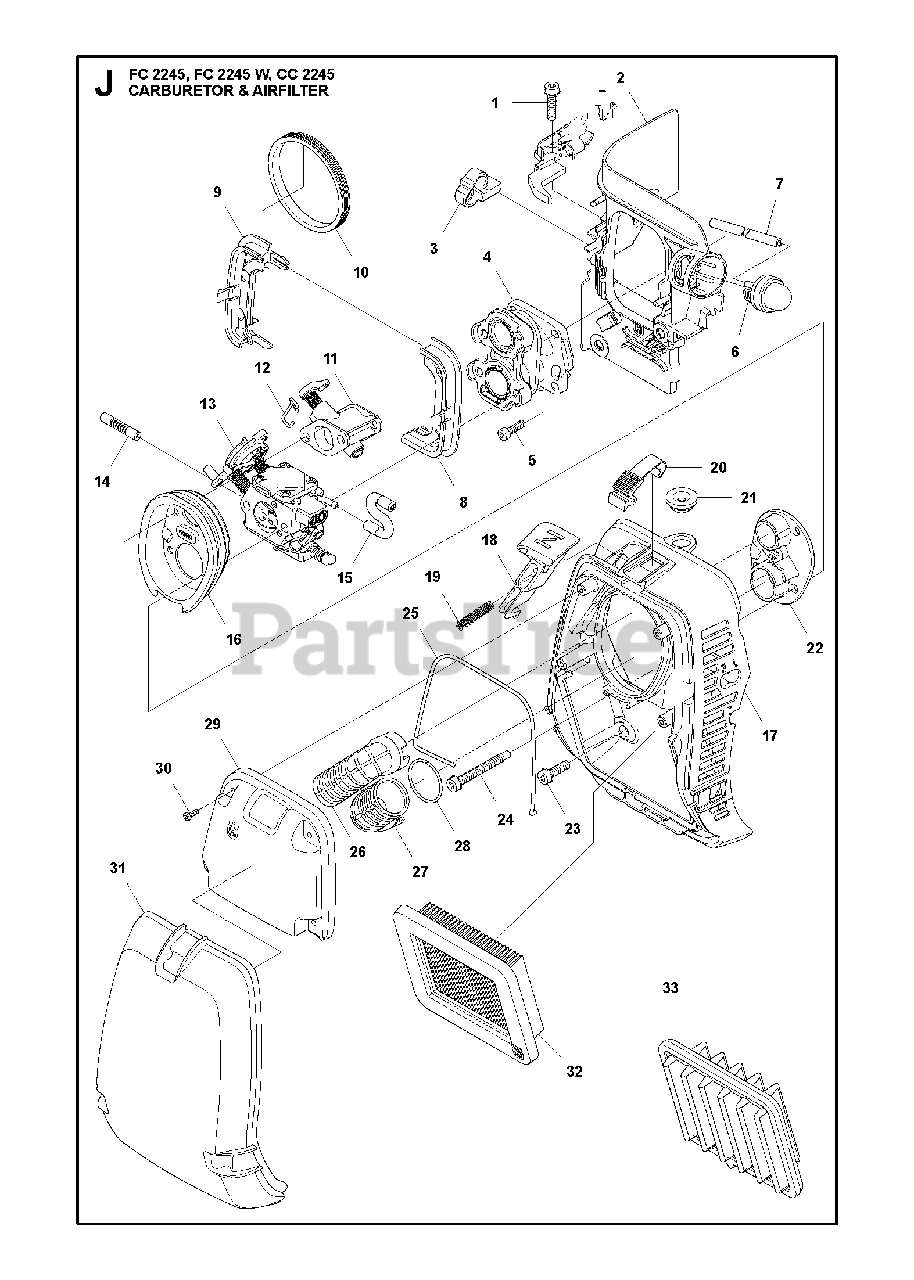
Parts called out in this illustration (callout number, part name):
2	INSULATION WALL
4	INLET PIPE
6	AIR PURGE BUBBLE
10	SEALING RING
13	CARBURETOR
14	SUCTION HOSE
15	FUEL HOSE
17	FILTER HOLDER ASSY
18	CHOKE CONTROL
22	COVER PLATE
23	SCREW IHSCFM
26	AIR INLET
27	AIR INLET
28	LOCKING SPRING
31	FILTER COVER
32	FILTER
33	FILTER
